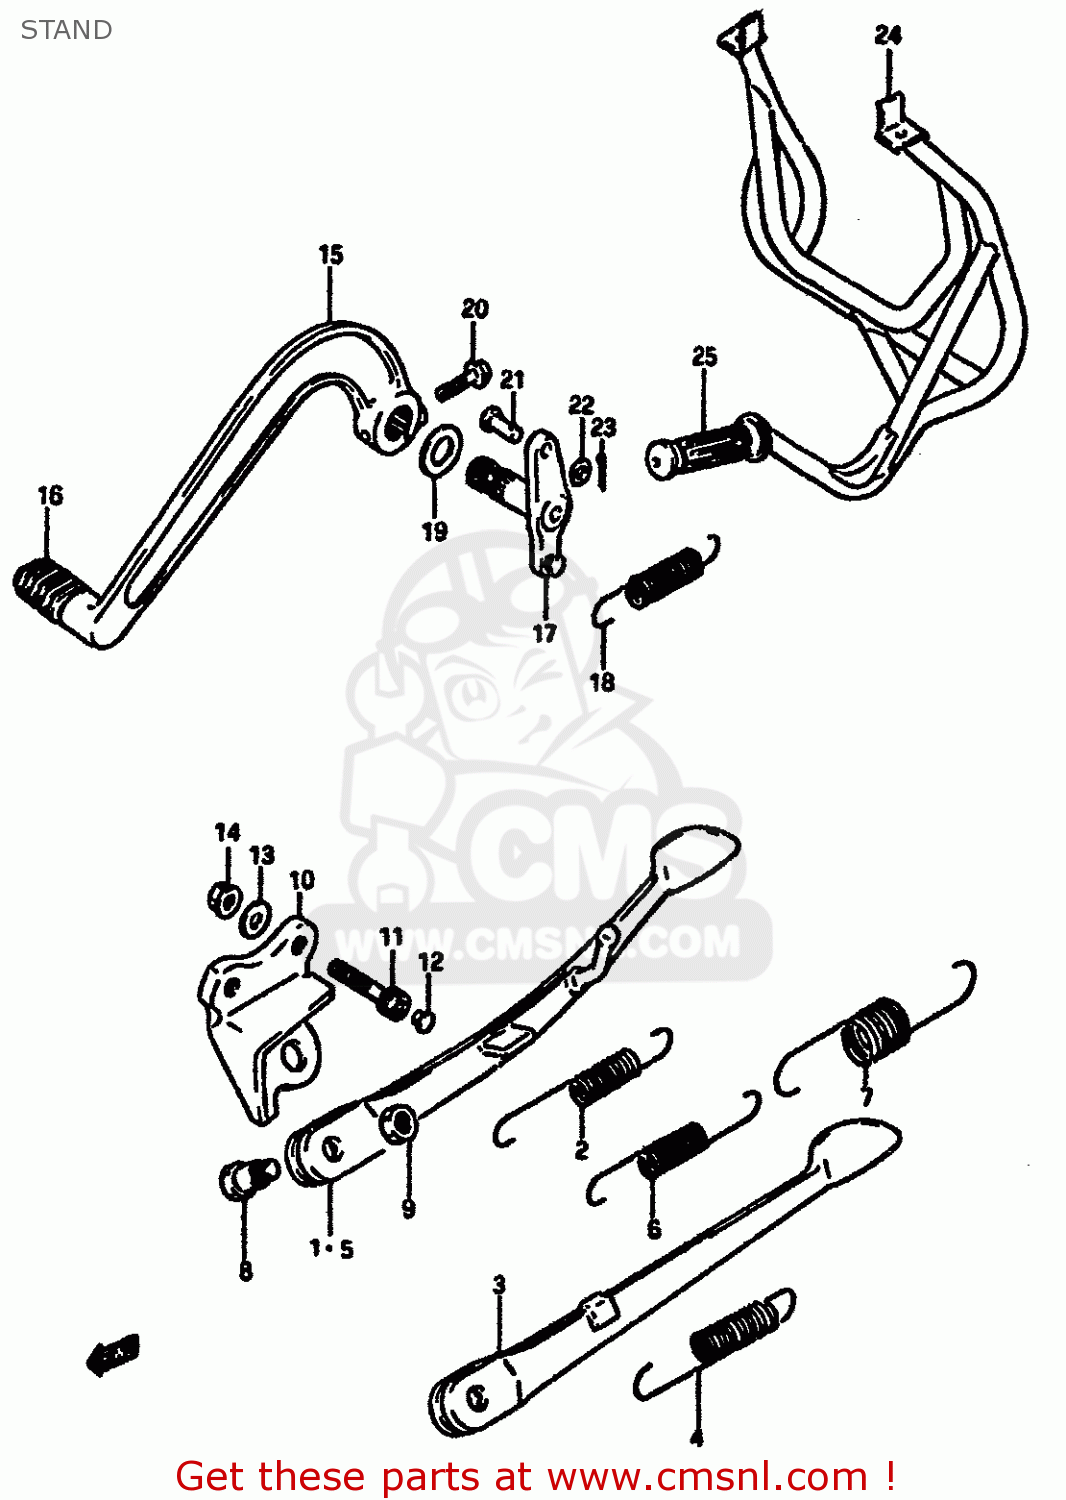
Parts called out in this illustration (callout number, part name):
1	STAND,SIDE
2	SPRING
3	STAND,PROP (SILVER)
4	SPRING
5	STAND,PROP (SILVER)
6	SPRING
7	SPRING
8	BOLT(10X38)
9	NUT
10	BRACKET,SIDE STAND
11	BOLT, FRONT RH
12	CAP,ENGINE MOUNTING
13	WASHER
14	NUT
15	PEDAL,BRAKE
16	RUBBER,BRAKE PEDAL
17	ARM COMP,BRAKE ROD
18	SPRING
19	WASHER,BRAKE PEDAL
20	BOLT
21	PIN
22	WASHER
23	PIN
24	STAND,CENTER
25	GRIP,L
